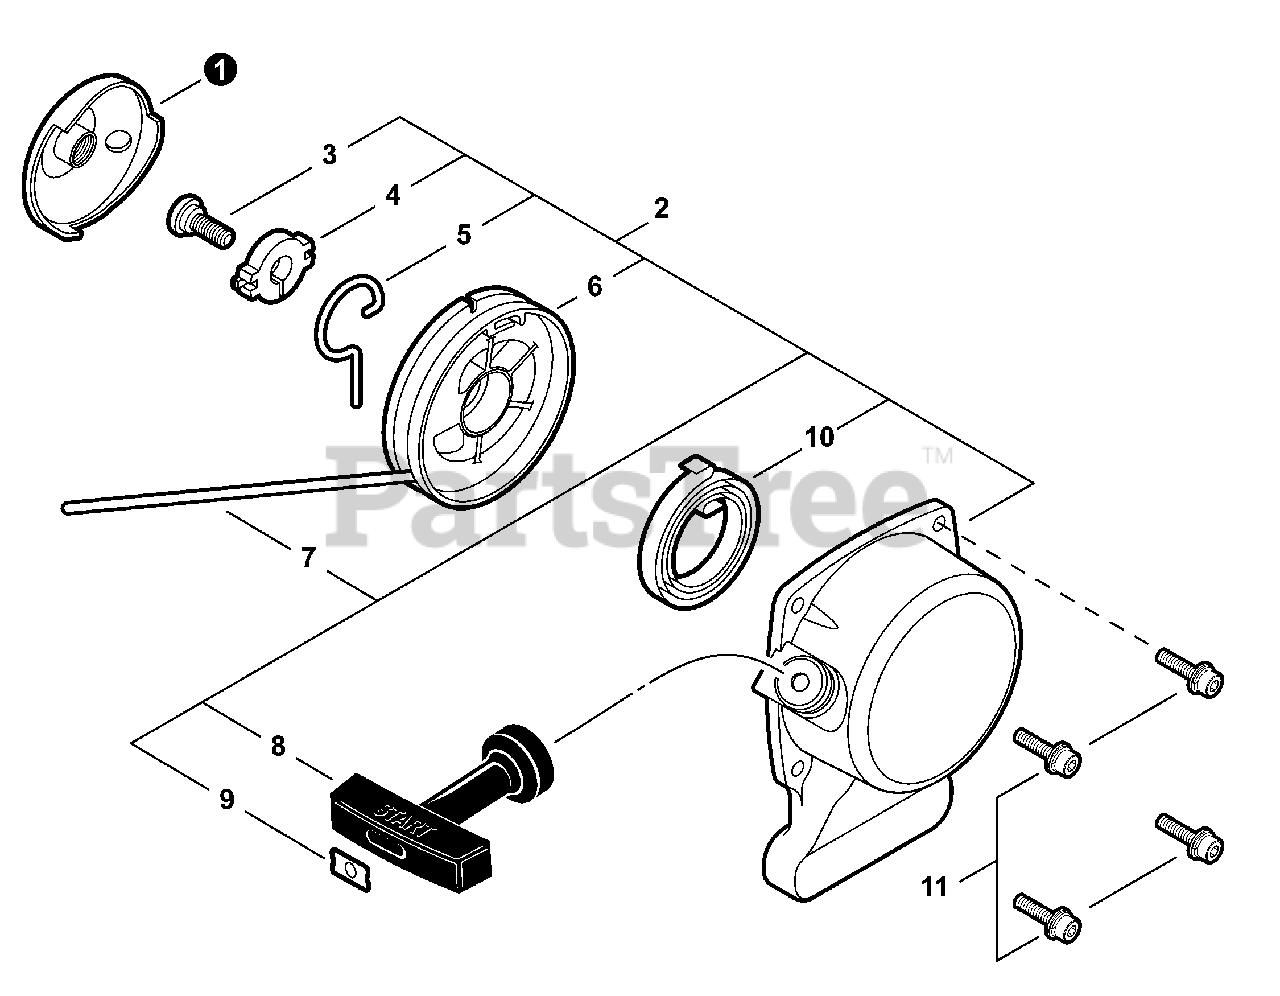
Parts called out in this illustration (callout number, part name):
1	PULLEY, STARTER
2	STARTER ASSY, RECOIL
3	SCREW 5
4	WASHER 5
5	ARM, SWING
6	REEL, ROPE
7	ROPE, STARTER
8	GRIP, STARTER
9	RETAINER, ROPE
10	SPRING, RECOIL
11	BOLT M4×14
